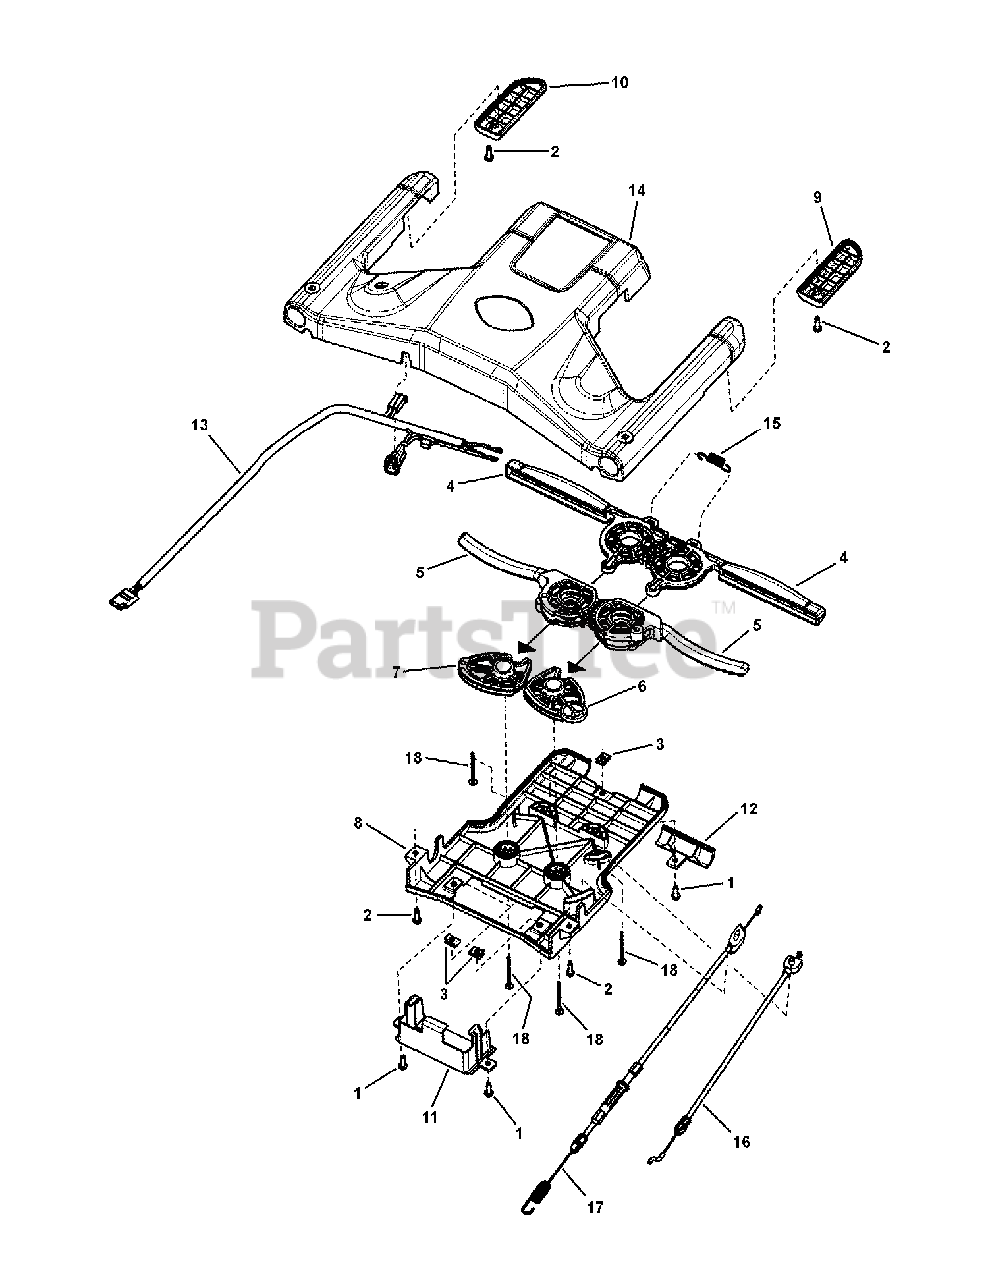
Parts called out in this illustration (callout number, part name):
1	SCREW, #10-24 x 5/8" Hex Washer Self-Tap, GR 5 BZ
2	SCREW, #10-16 x 3/4" Pan Head Self-Tap Combo, BZ
3	NUT, #10-24 Speed Retainer w/extrusion
4	LEVER, Drive Control
5	LEVER, OPC, Control
6	CAM, Drive, LH
7	CAM, Drive, RH
8	CONTROL PANEL, Bottom, MY Mower
9	PANEL, Bottom Control, WBM, RH
10	PANEL, Bottom Control, WBM, LH
11	ACCESS DOOR, Battery Control Panel, WBM
12	PANEL, Access, Maintenance Reminder
13	HARNESS, Snapper React Drive
14	PANEL, Top Control
15	SPRING, Tension, Drive Control
16	CABLE, OPC, 2010 NXT
17	CABLE, Control, 2010 NXT
18	SCREW, #10-16 x 2" Hi-Lo Cross Pan Head
